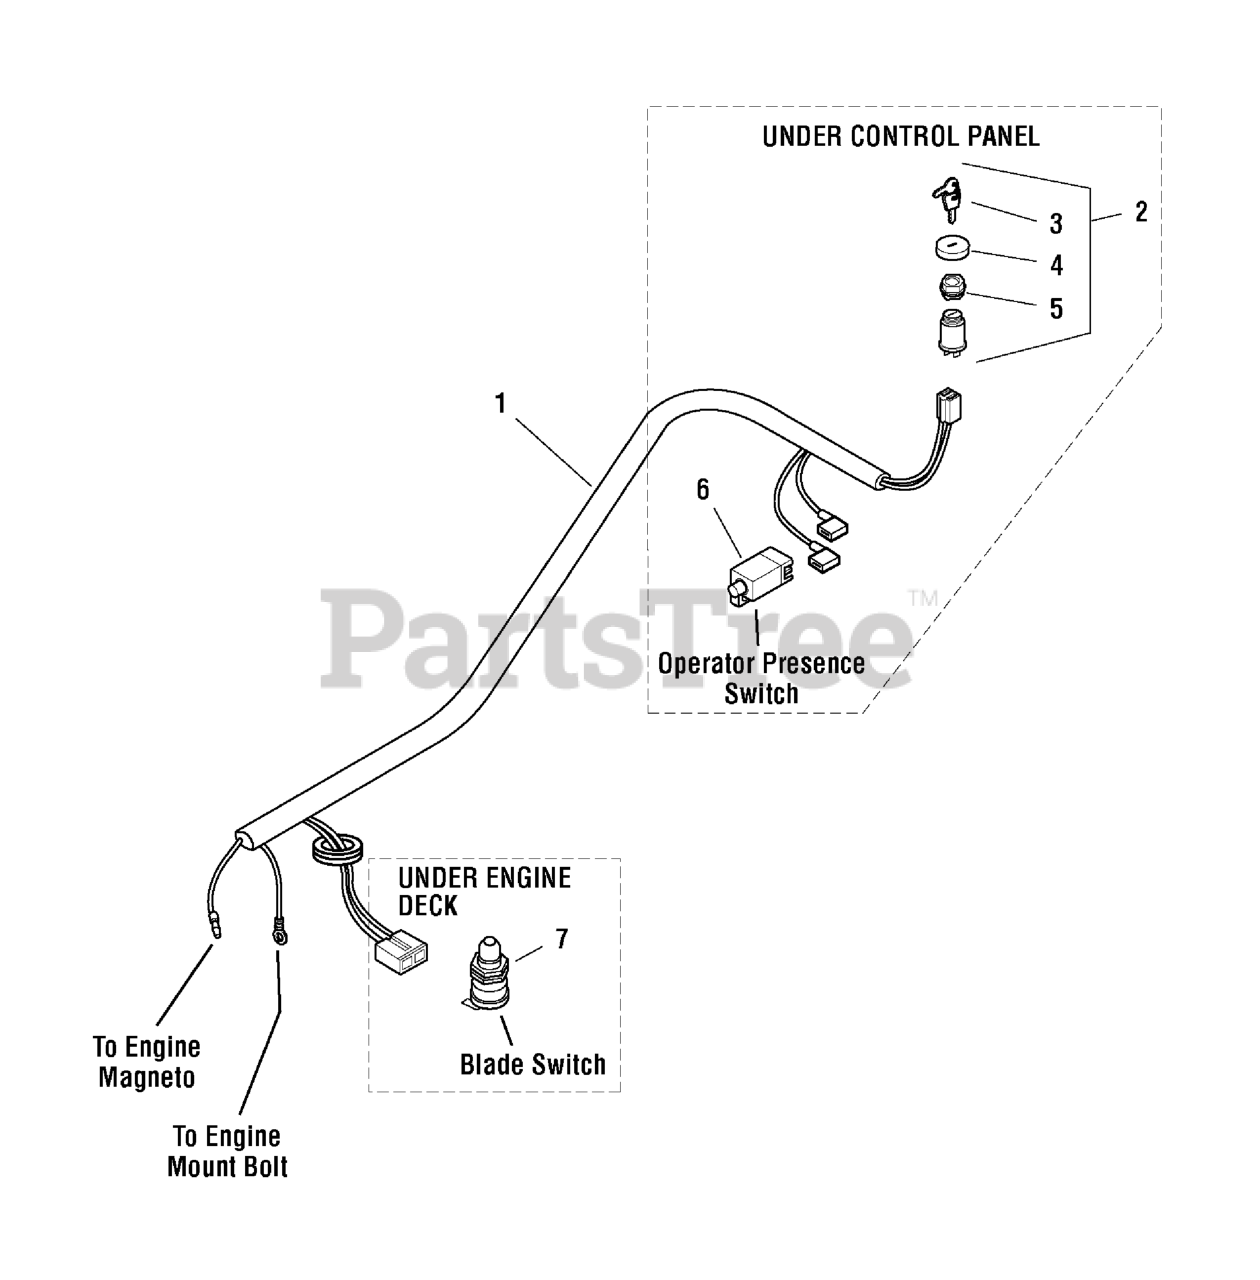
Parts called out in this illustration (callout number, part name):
1	WIRE HARNESS
2	SWITCH, Ignition, Complete
3	KEY, IGNITION MOLDED SET
4	COVER, PLASTIC, SNAP ON
5	PLASTIC NUT
6	SWITCH, PLUNGER, N.C.
7	SWITCH, Plunger, NC
